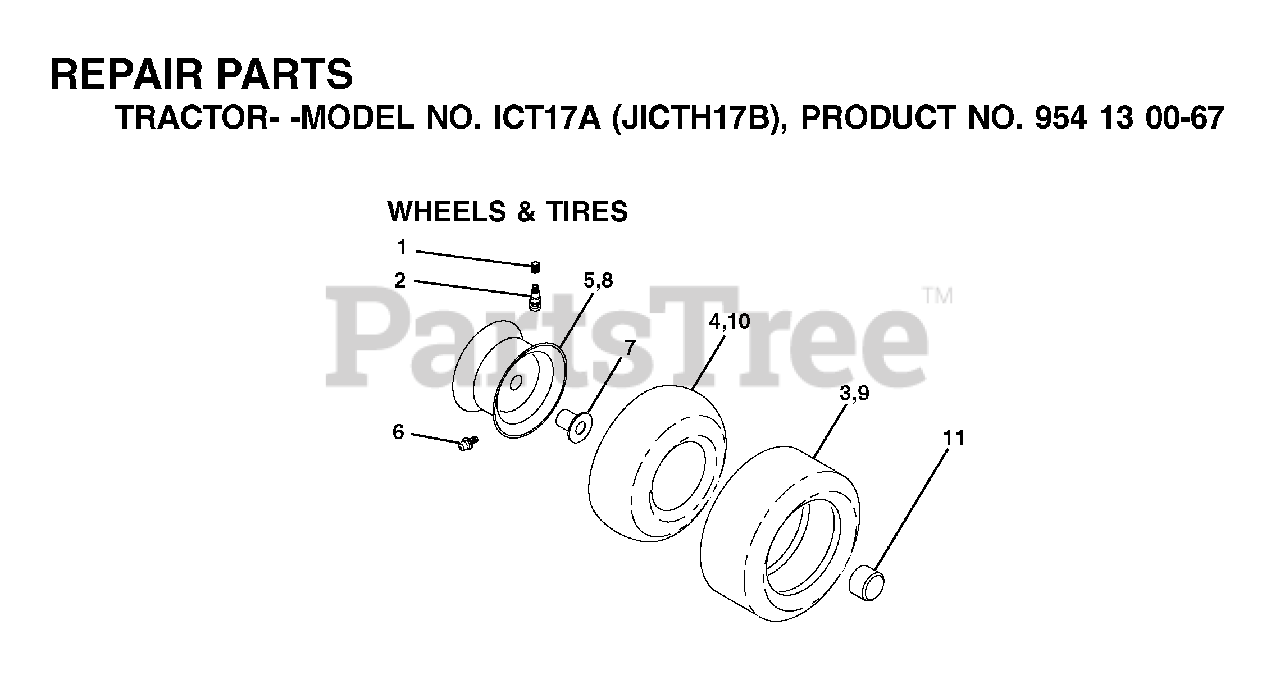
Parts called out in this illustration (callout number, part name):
1	VALVE CAP
2	VALVE STEM LT
3	TIRE HEAVY DUTY
4	TUBE.5.3/4.5/6
5	RIM ASM 6" FRONT SILVER
6	FITTING LT
7	BEARING T
8	RIM ASM 8" REAR SILVER
9	TIRE 20X8-8 TURF SAVER
10	TUBE
11	CAP, AXLE BLK
